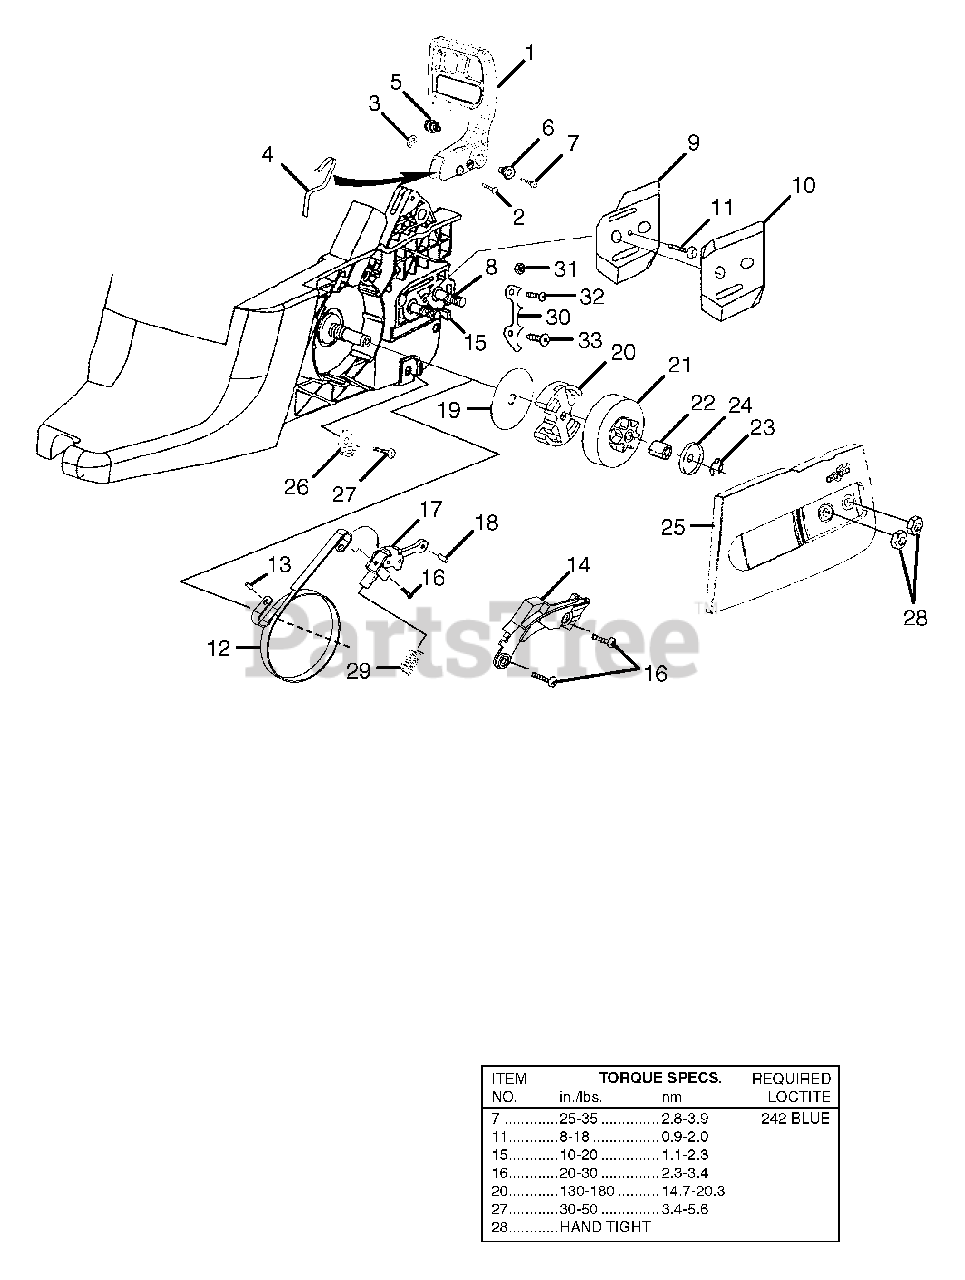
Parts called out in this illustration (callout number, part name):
1	HAND GUARD
2	HAND GUARD ACTUATING PIN
3	RETAINING RING
4	SPRING, HANDGUARD
5	PIVOT, LH
6	PIVOT, RH
7	SCREW (8-32 x 5/8 in.)
8	GUIDE BAR BOLT
9	PLATE, GUIDE BAR
10	PLATE, GUIDE BAR
11	SCREW (6-19 x 1/2 in.)
12	BRAKE BAND
13	PIN, ROLL
14	BRAKE BAND COVER
15	ADJUSTING PIN KIT
16	SCREW (8-16 x .320 )
17	CHAIN BRAKE LINK
18	PIN, ROLL
19	THRUST WASHER
20	CLUTCH & HARDWARE
21	SPROKET DRUM (.325 PITCH)
22	BEARING, NEEDLE
23	RING, RETAINING
24	WASHER
25	DRIVE CASE COVER
26	CHAIN CATCHER
27	SCREW (10-24 x 1/2 in.)
28	NUT, HEX
29	SPRING, COMPRESSION
30	BUMPER SPIKE
31	LOCK NUT, HEX (10-24)
33	SCREW, TRUSS HD.
